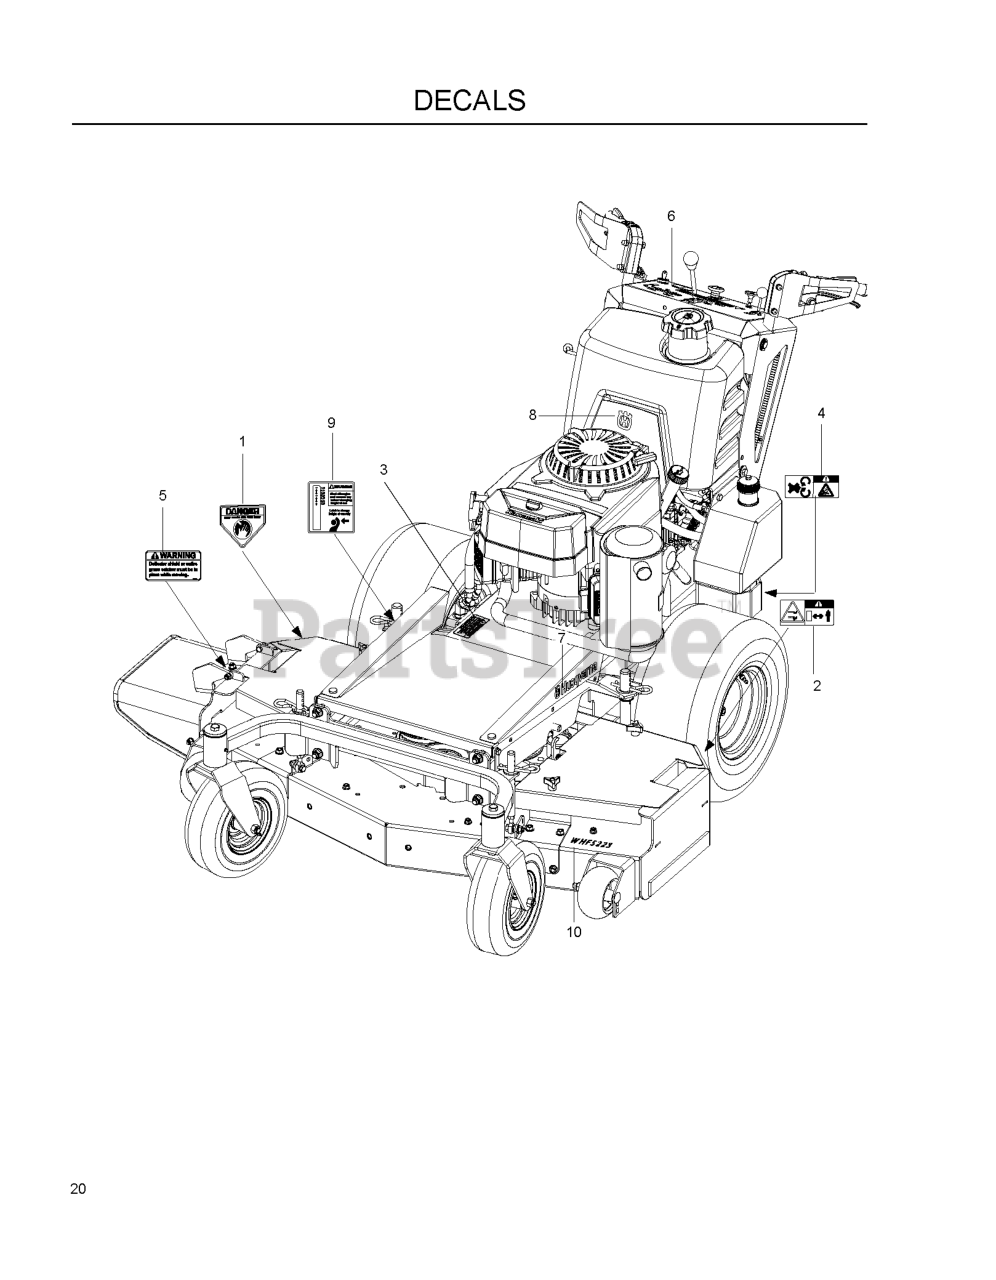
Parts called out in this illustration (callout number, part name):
1	HCS 1/2C X 5 1/2
2	CASTER YOKE - PAINTED
3	NUT 1/2-13 HEX NYLOC ZD
4	TIRE/WHEEL.CASTER
5	TIRE - CASTER
6	VALVE STEM TR-412
8	ZERK
9	BEARING RETAINER
12	BEARING FLANGED
13	HEAVY WASHER
14	HHCS 1/2-13 X 1
